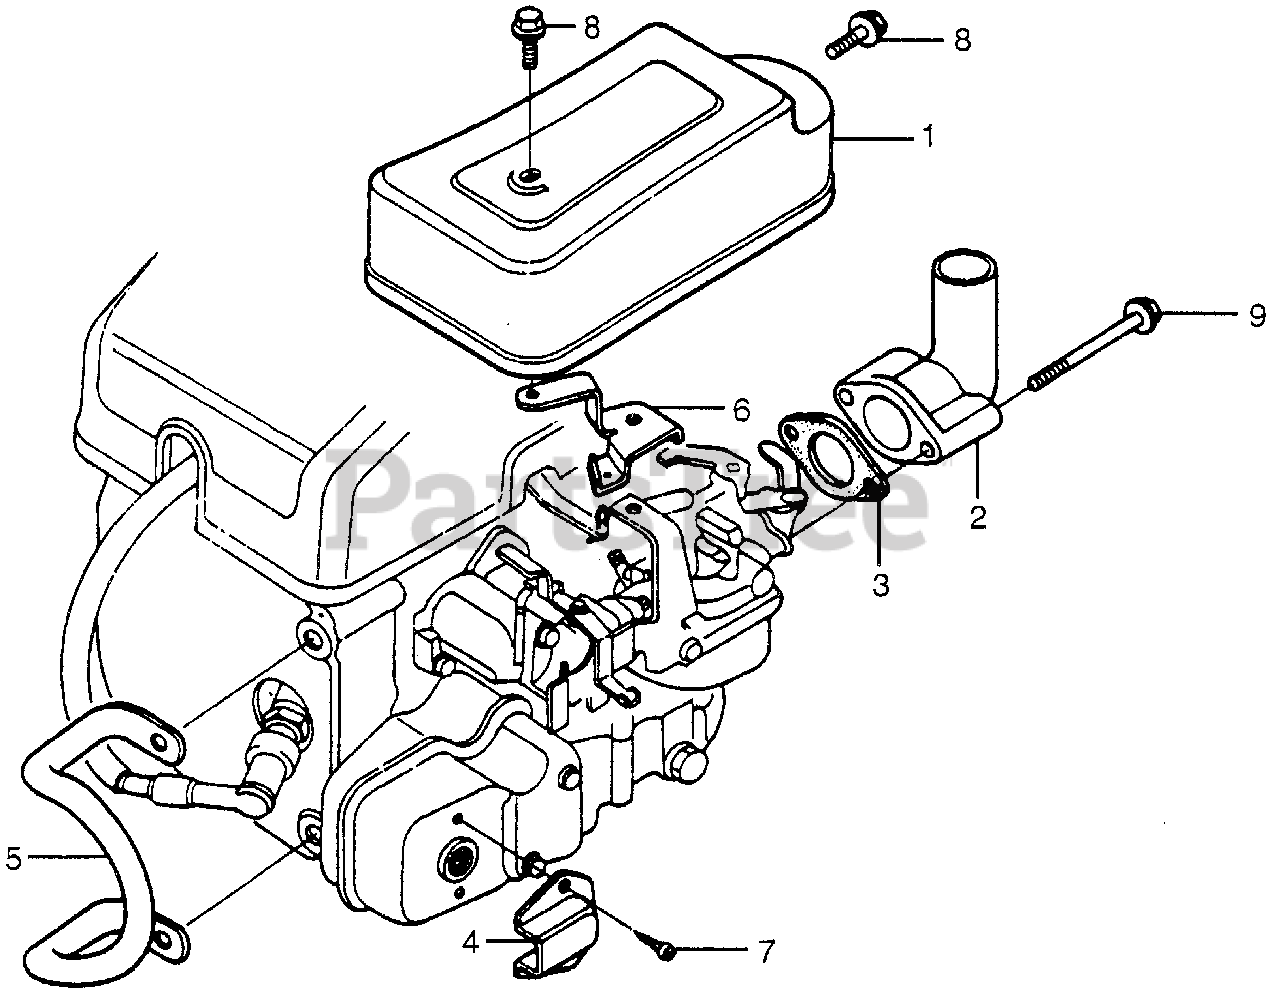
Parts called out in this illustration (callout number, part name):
1	COVER, CARBURETOR
2	ELBOW, CLEANER
3	GASKET, AIR CLEANER ELBOW
4	DEFLECTOR, MUFFLER
5	GUARD, PLUG
6	STAY, ENGINE SWITCH
7	SCREW, TAPPING (5X8)
8	BOLT, FLANGE (6X12)
9	BOLT, FLANGE (6X50)
